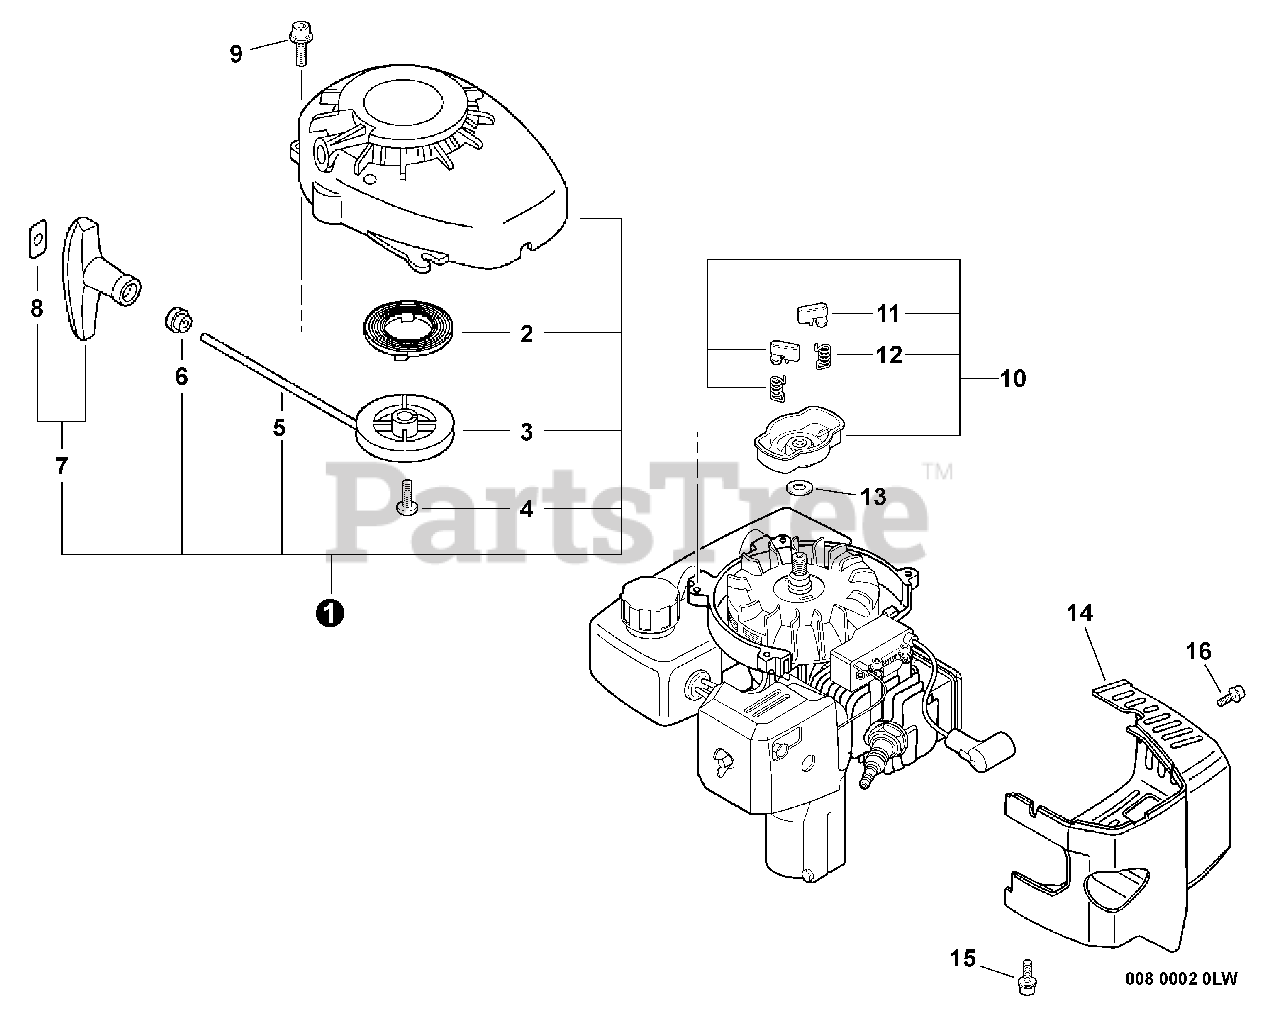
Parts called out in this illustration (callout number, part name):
1	STARTER ASSY
2	SPRING, REWIND
3	REEL, ROPE
5	ROPE, STARTER - 3X890
6	GUIDE, ROPE
7	GRIP, STARTER
8	RETAINER, ROPE
9	SCREW - 4X16
10	STARTER PAWL ASSY
11	PAWL, STARTER - BLACK
12	SPRING, RETURN
13	LOCKWASHER - 8
14	COVER, ENGINE
15	SCREW - 4X18
16	SCREW - 4X8
